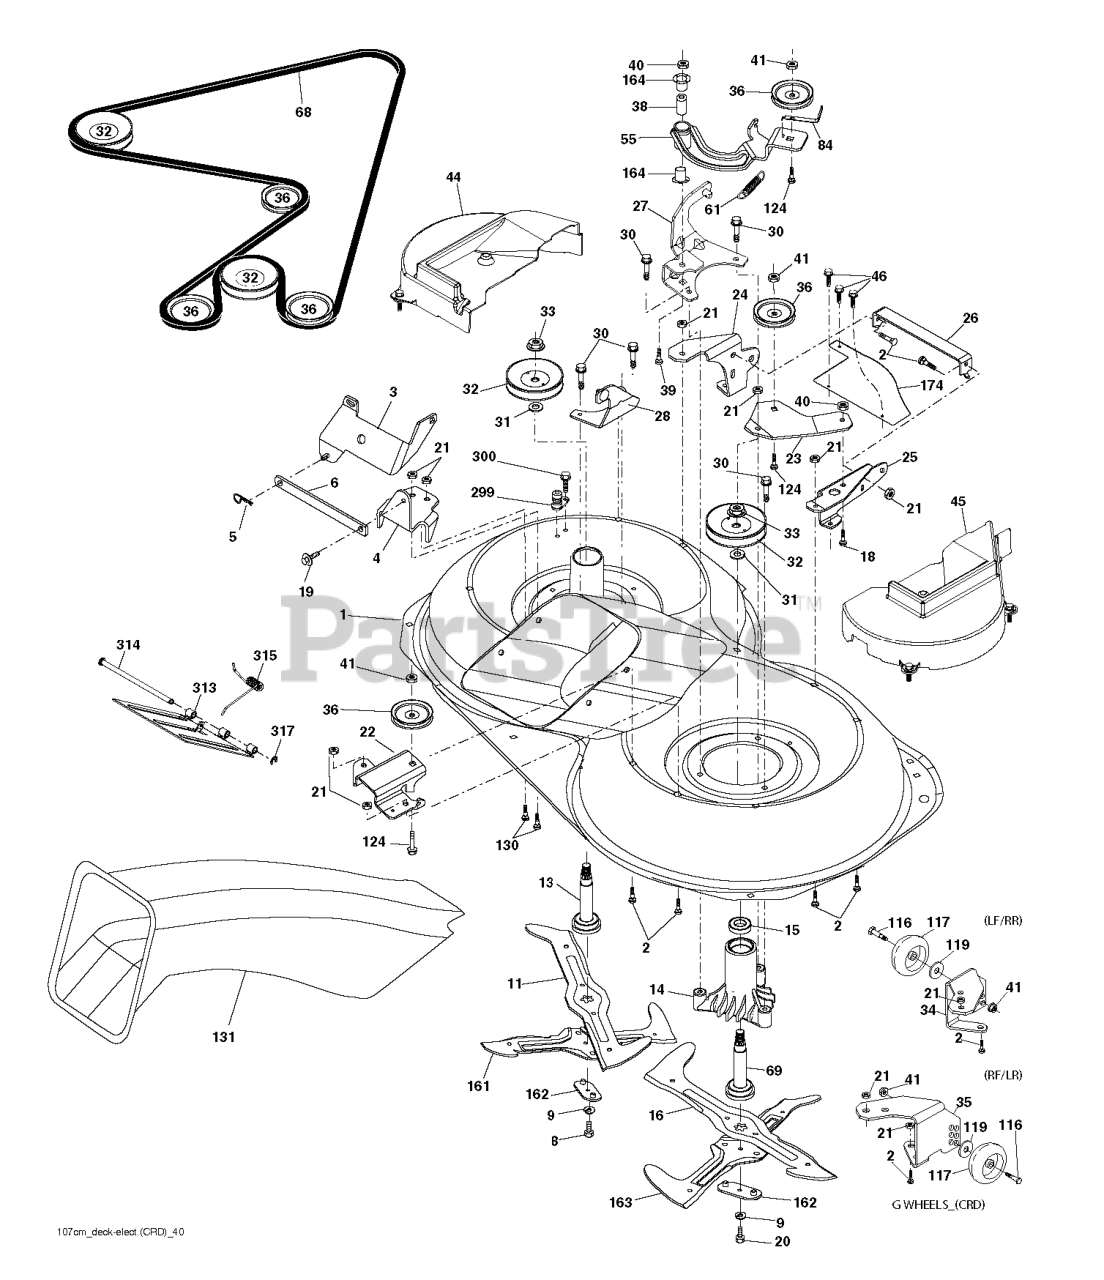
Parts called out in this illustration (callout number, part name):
2	RP BOLT 5/16-18 X3/4 ZN/YEL GR
5	RETAINER-SPRNG RB
6	BAR.SWAY.92.CRD
8	BOLT.3/8-24X1.25 GR8
9	LOCKWASHER
11	BLADE.3N1.LH.CRD
13	SHAFT ASM VENT
14	HOUSING.MANDREL.VENTED (MACHD)
16	BLADE.3N1.RH.CRD
19	BOLT SHD 5/16-18
20	BOLT.3/8-24X1.25GR8. LHTHRD
21	LOCKNUT
22	BRACKET.IDLER.RR.107.CRD
24	BRACKET
25	BRACKET RF
26	SUPPORT
28	BRACKET
30	SCREW, WASHER HEAD
31	WASHER.SPACER.MANDREL
32	PULLEY.MANDREL.4.80 PD.2006
33	NUT.FLANGE.LOCK.TOP
34	BRACKET
35	BRACKET
36	PULLEY.IDLER.4.25
41	NUT LOCK FLG 3/8-16 UNC
44	COVER MANDREL LEFT
45	COVER MANDREL RIGHT
46	SCREW.1/4-20X5/8
55	ARM.IDLER.107.CRD
61	SPRING
68	HEX-BELT 107 MOWER
69	SHAFT.ASM.W/LWR.BRG.RH.THREAD
84	KEEPER, BELT IDLER
116	BOLT.SHOULDER.3/8-16X3-5/8.
117	RP WHEEL. GUAGE RALLY
119	WASHER
124	BOLT.3/8-16X1.50
130	BOLT.CARR.SQNK.5/16-18UNC.X3/4
163	BLADE.CROSS.RH.CRD.107
164	BRNG T
174	PLATE
299	PORT.WASHOUT
300	SCREW.TT.#10-32X.5.3/8.FLANGE
313	COVER DOOR.107 CM CRD EZ MULCH
314	PIN PIN.HINGE
317	E-RING.5/16"
